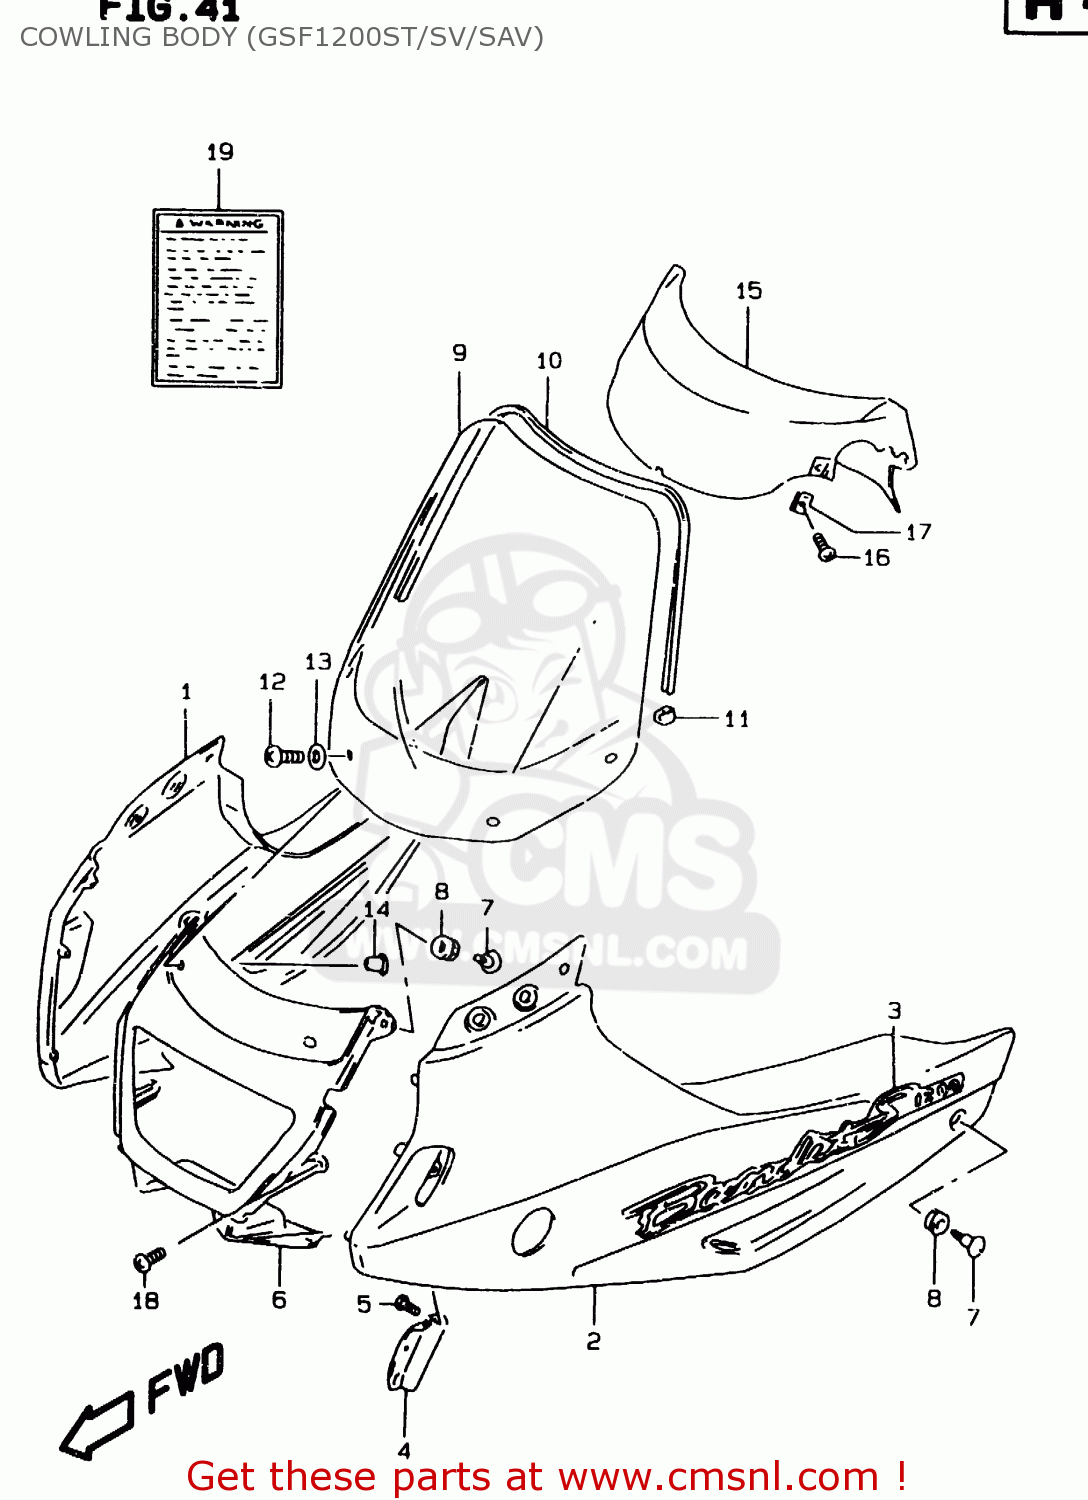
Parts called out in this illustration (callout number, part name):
1	COWLING ASSY,SIDE,R
2	COWLING ASSY,SIDE,L
3	EMBLEM,COWLING SIDE
4	COVER,COWLING INNER,R
5	SCREW 5X10
6	COWLING ASSY,CTR
7	SCREW(6X20)
8	CUSHION
9	WINDSCREEN SET
10	MOLDING WINDSCREEN
11	CLIP,WINDSCREEN MOLDING
12	SCREW(5X14)
13	WASHER
14	NUT
15	PANEL,INNER
16	SCREW
17	NUT
18	SCREW
19	LABEL (WARNING SCREEN)
